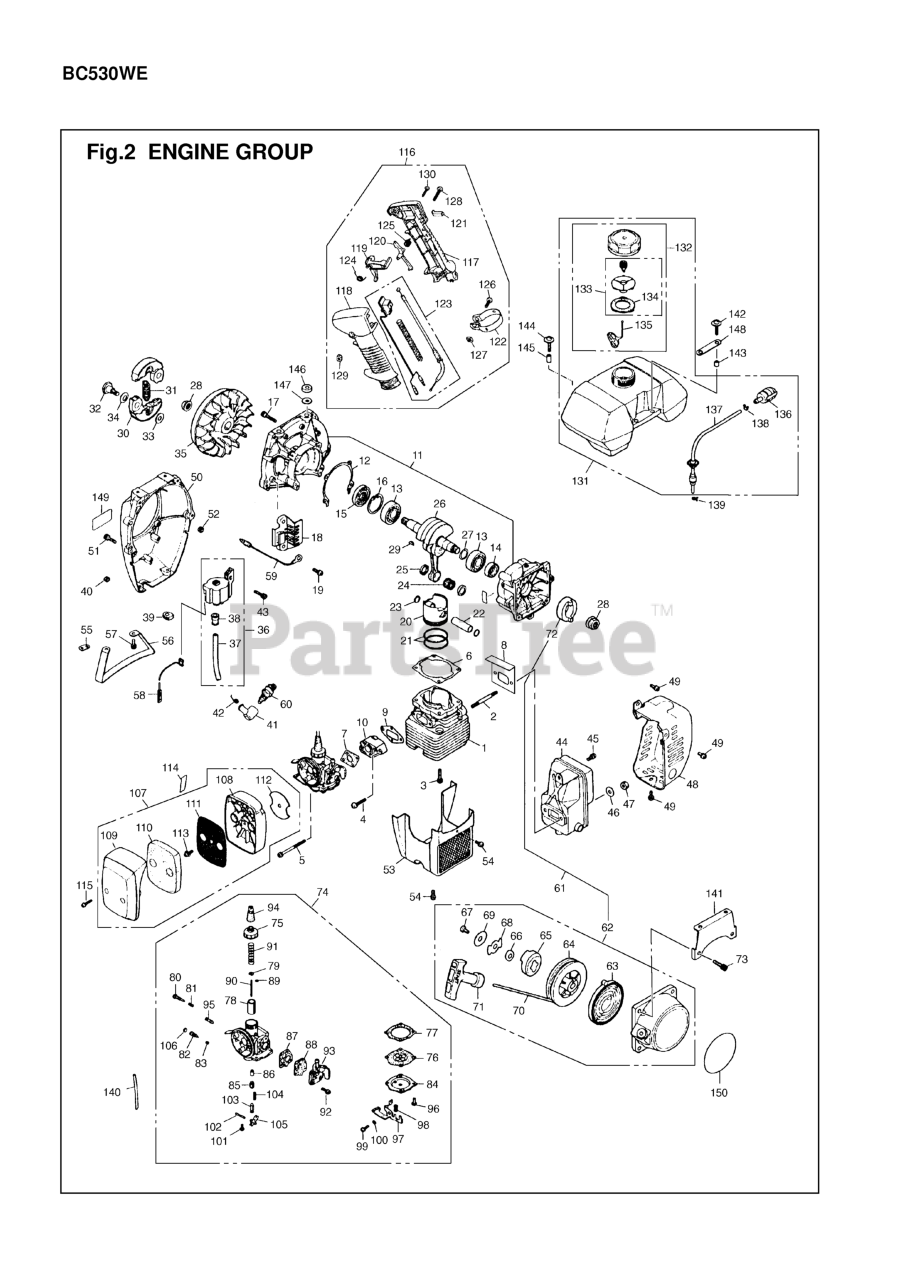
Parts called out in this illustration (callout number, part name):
1	CYLINDER
3	BOLT
10	INSULATOR
11	CRANKCASE COMPLETE
14	SEAL, OIL - STARTER SIDE
16	RING, SNAP, M35 X 1.5
17	BOLT, M5 X 30
18	GUARD (RPLS-21310)
20	PISTON
21	RING
22	PIN, PISTON
23	RING
24	BEARING
25	WASHER, THRUST
26	SHAFT (RPLS -42001)
27	SHIM
28	NUT
29	KEY
30	SHOE (RPLS -51112)
32	SCREW
33	WASHER
34	WASHER (USE -51241)
37	CORD, HIGH TENSION
38	CAP
39	GROMMET
42	SPRING
46	WASHER
50	COVER, FAN (REPLACES -31111)
51	BOLT
53	CYLINDER COVER
57	BOLT
59	EARTH CORD
63	SPRING
65	DOG
66	WASHER
67	SCREW
68	RETAINER
69	WASHER
70	ROPE
71	KNOB
72	PULLEY
75	CAP (RPLS -81121)
76	DIAPHRAGM ASSY.
77	PACKING
78	VALVE, THROTTLE
79	RECEIVER
81	SPRING, ADJUST
82	SCREW (REPLACES 1420-81270)
83	SPRING, MJ,ADJ
84	COVER, DIAPHRAM
85	HOLDER, NEEDLE
86	JET, NEEDLE
87	PACKING, PUMP
88	DIAPHRAGM
89	CLIP (USE 1030-81000-16)
93	COVER ASS
97	LEVER, TICKLER
98	SPRING, TACKLE
103	VALVE NEEDLE
104	SPRING, HINGE
105	HINGE, VALVE
107	CLEANER ASSY
108	BODY (RPLS -82111)
110	ELEMENT (REPLACES 1400-82130)
111	SCREEN
114	LABEL
119	LEVER
120	LEVER
122	BAND
123	CABLE COMP
124	SPRING
125	SPRING
127	NUT
129	NUT
130	SCREW
131	TANK ASSY
132	CAP ASSY
133	VALVE COMP
134	PACKING (RPLS -85321)
135	STOPPER (RPLS 3317-57240)
136	FILTER ASSY (W/CHECK VALVE)
137	PIPE, FUEL (W/ PRIMARY PUMP)
138	CLIP
141	SUPPORT (RPLS -86213)
147	WASHER (USE 181741)
149	LABEL, COVER
